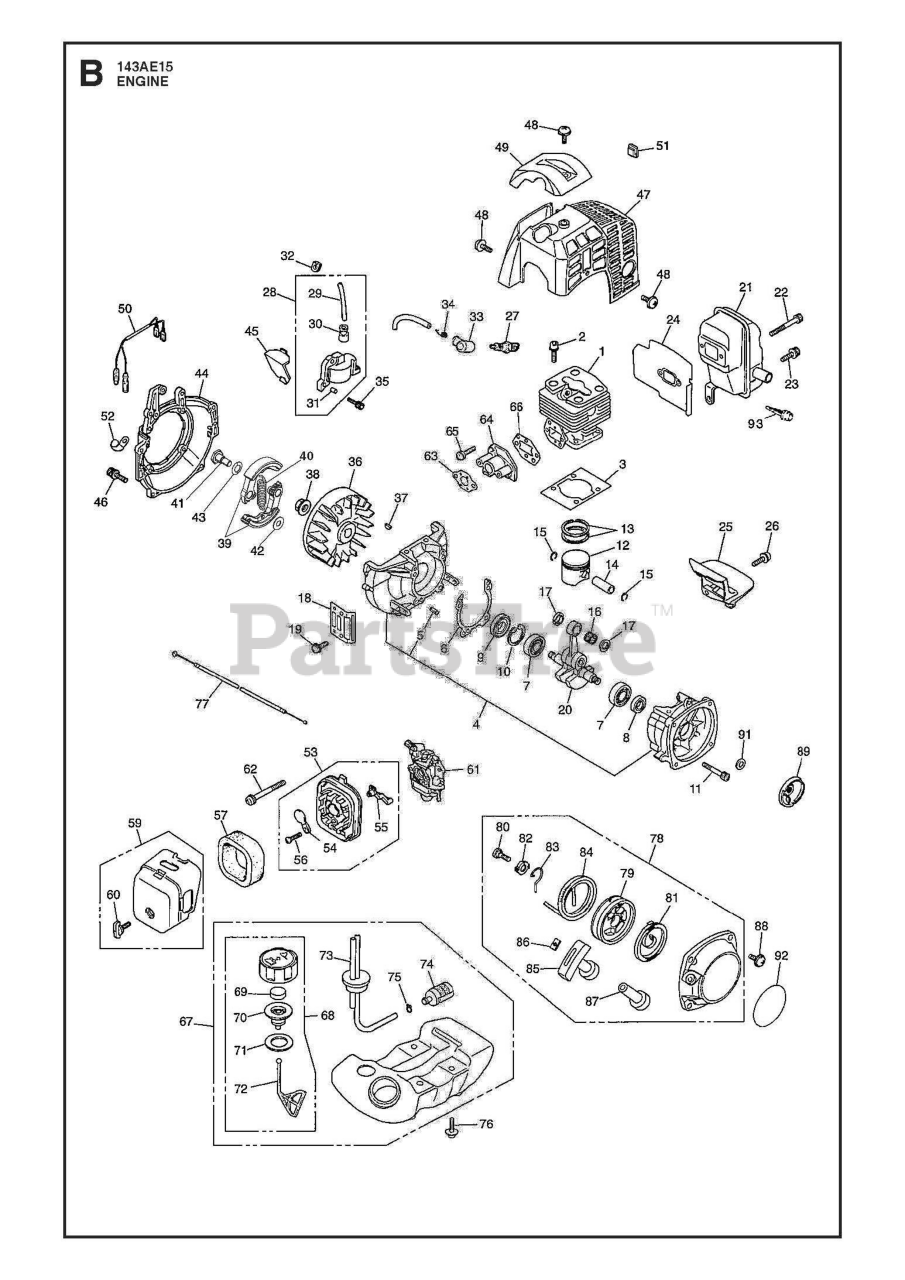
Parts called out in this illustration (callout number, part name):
13	RING, PISTON 2/PK
14	PISTON PIN
16	ROLLER BEARING
25	PLATE.MUFFLER
30	CAP
32	GROMMET
38	NUT
50	CORD COMPLETE
52	CLAMP
53	BODY ASSY.
54	PLATE, CHOKE
55	LEVER.CHOKE
56	SCREW
61	CARBURETOR-A
67	TANK ASSY (RPLS -85004)
73	PIPE COMP.
74	FILTER ASSY
77	CABLE COMP.
81	SPRING, SPIRAL
93	ARRESTER
